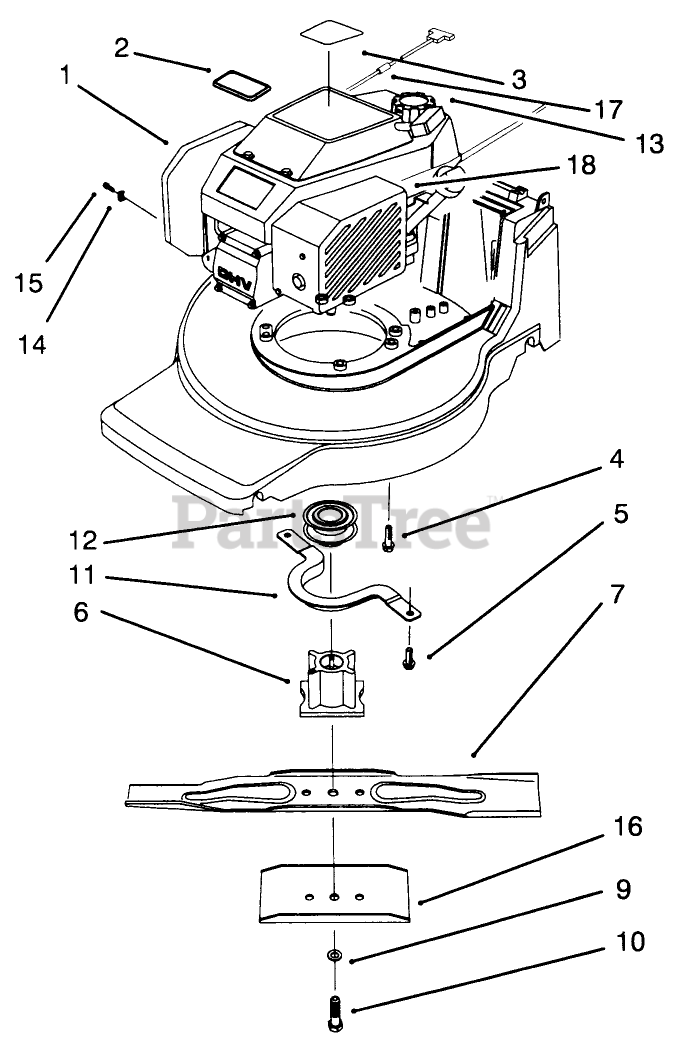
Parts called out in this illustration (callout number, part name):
4	SCREW-HWH
5	SCREW-HWH
7	Blade
9	WASHER-LOCK
10	BOLT-BLADE
12	PULLEY-DRIVE, ZONE START
13	GAS CAP ASM
14	CLAMP-CASING
15	CLAMP SCREW F/W ENGINE
16	Stiffener Blade
17	STOP-ROPE
